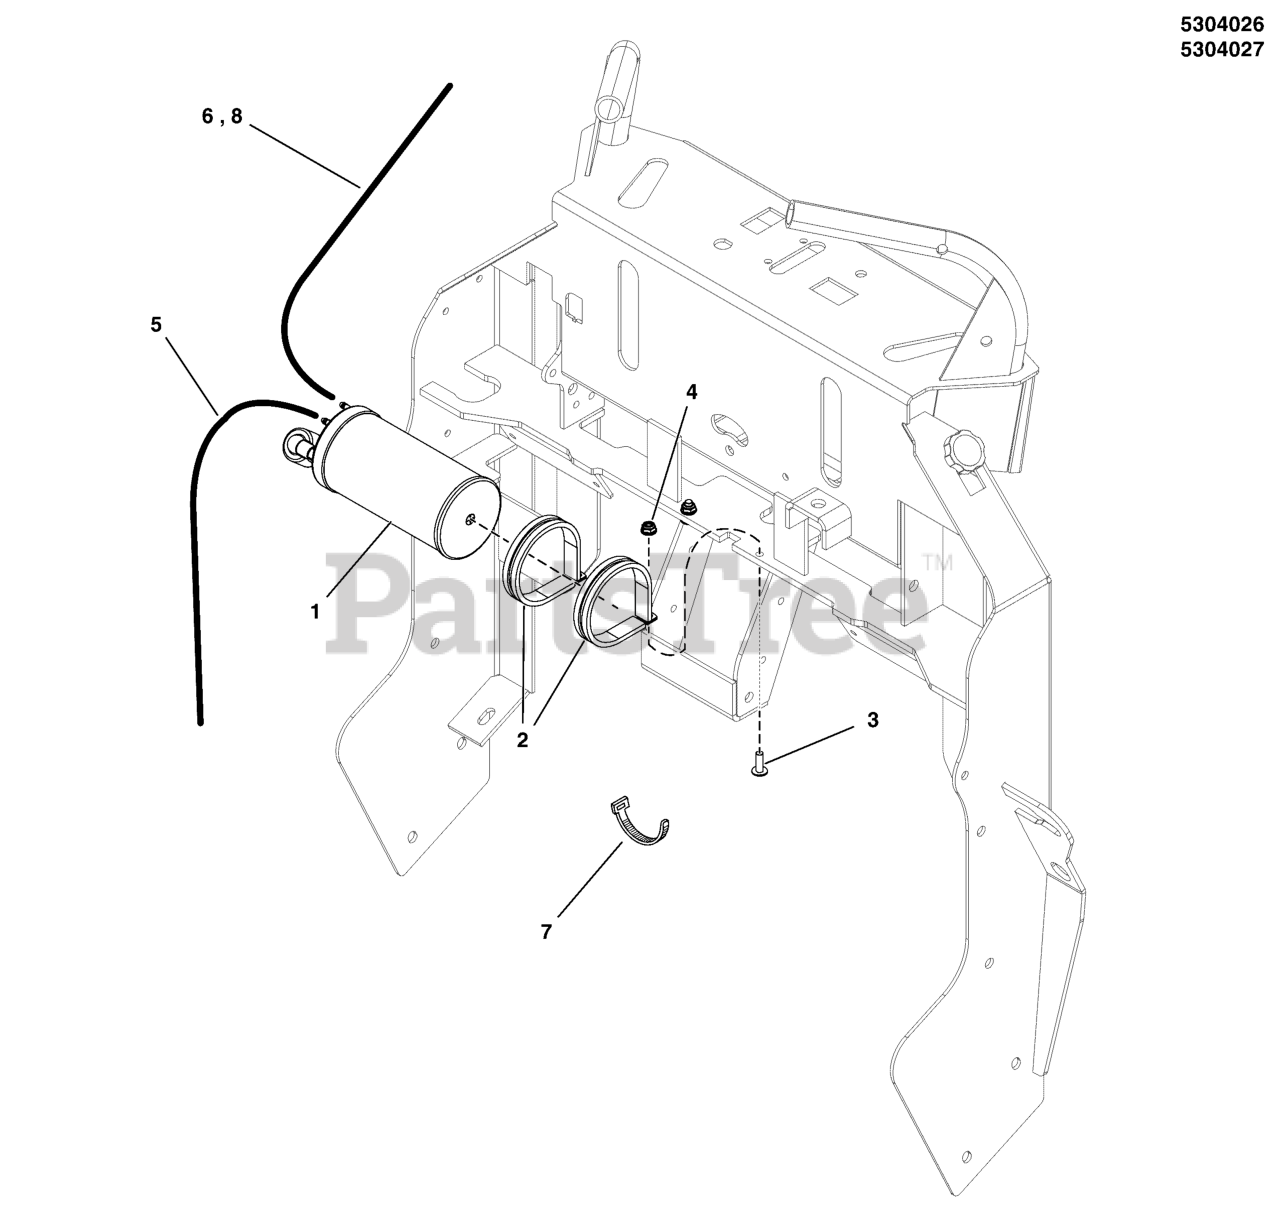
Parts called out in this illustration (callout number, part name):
1	CNSTR, CARB, 6 GAL
2	CLAMP, 3" ID, CUSHIONED, STAINLESS
4	NUT, 1/4-20 HEX NYLOCK FLANGE
5	HOSE, VAPOR, 5MM ID, 25.00 LG
6	HOSE, VAPOR, 5MM ID, 28.00 LG
7	TIE,SELF-LOCKING, 6"
8	HOSE, VAPOR, 5MM ID, 31.00 LG
